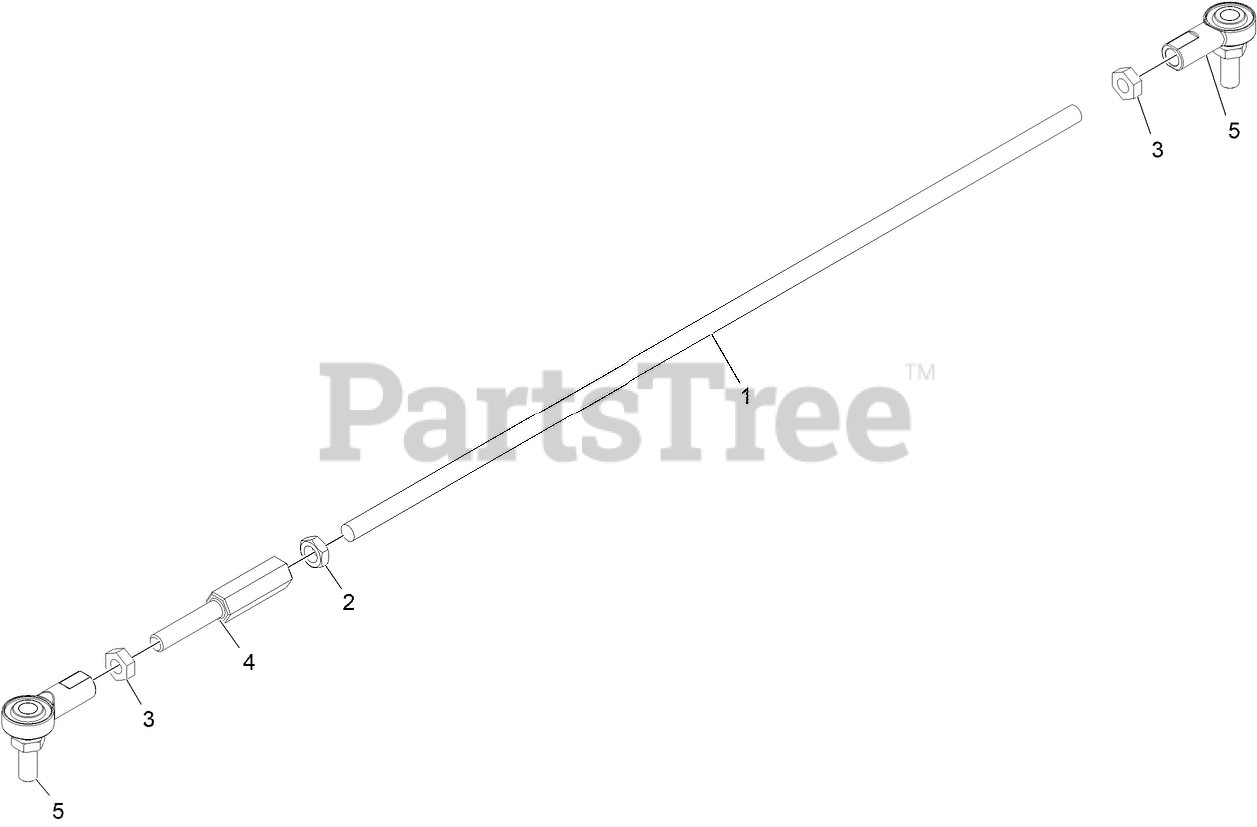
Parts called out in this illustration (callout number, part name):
1	ROD-MOTION CONTROL LONG
2	NUT-JAM
3	NUT-JAM
4	ROD-ADJUST
5	BALLJOINT
